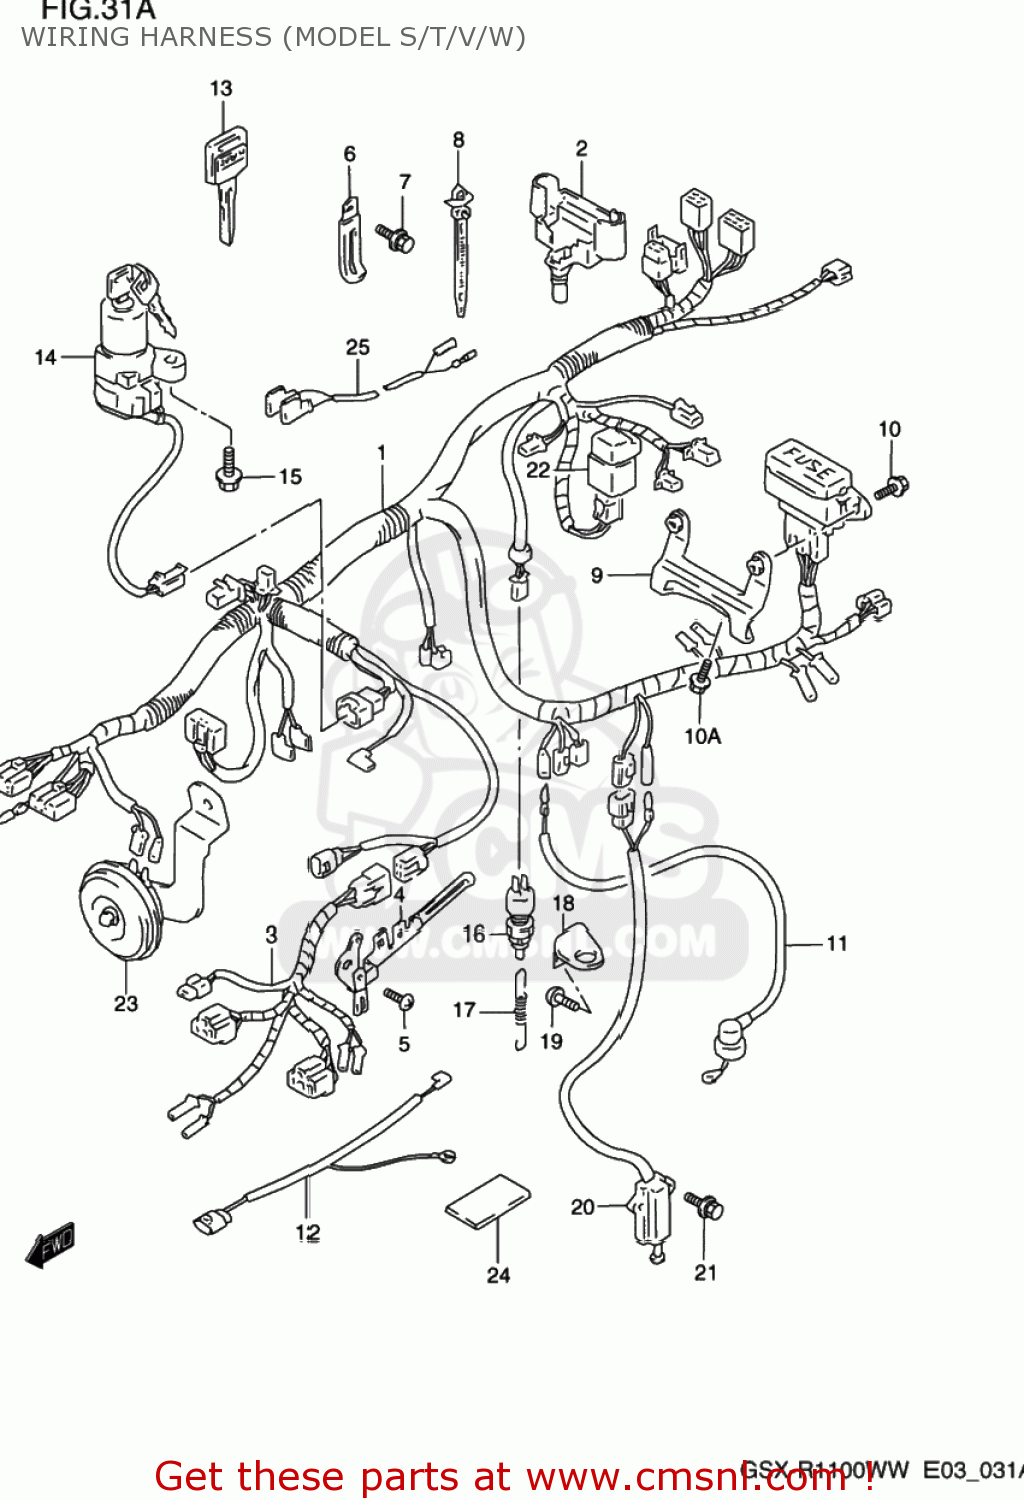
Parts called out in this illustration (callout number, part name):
1	HARNESS,WIRING
2	CAP,STARTER RELAY
3	HARNESS,WIRING NO.2
4	HOLDER COMP,COUPLER,LEFT
5	SCREW 5X8
6	CLAMP(L:65)
7	BOLT
8	CLAMP(L:95)
9	BRACKET,FUSE BOX
10	SCREW 6X12
10A	BOLT
11	WIRE,OIL PRESSURE SWITCH LEAD
12	WIRE,WATER TEMPERATURE GAUGE
13	KEY,BLANK
14	LOCK ASSY,STEERING
15	BOLT M8X20
16	SWITCH ASSY,STOP LAMP
17	SPRING
18	BRACKET,STOP LAMP SWITCH
19	SCREW(6X12)
20	SWITCH ASSY,SIDE STAND WARNING
21	BOLT
22	RELAY ASSY
23	HORN ASSY
24	TAPE
25	WIRE,CLUTCH LEAD
